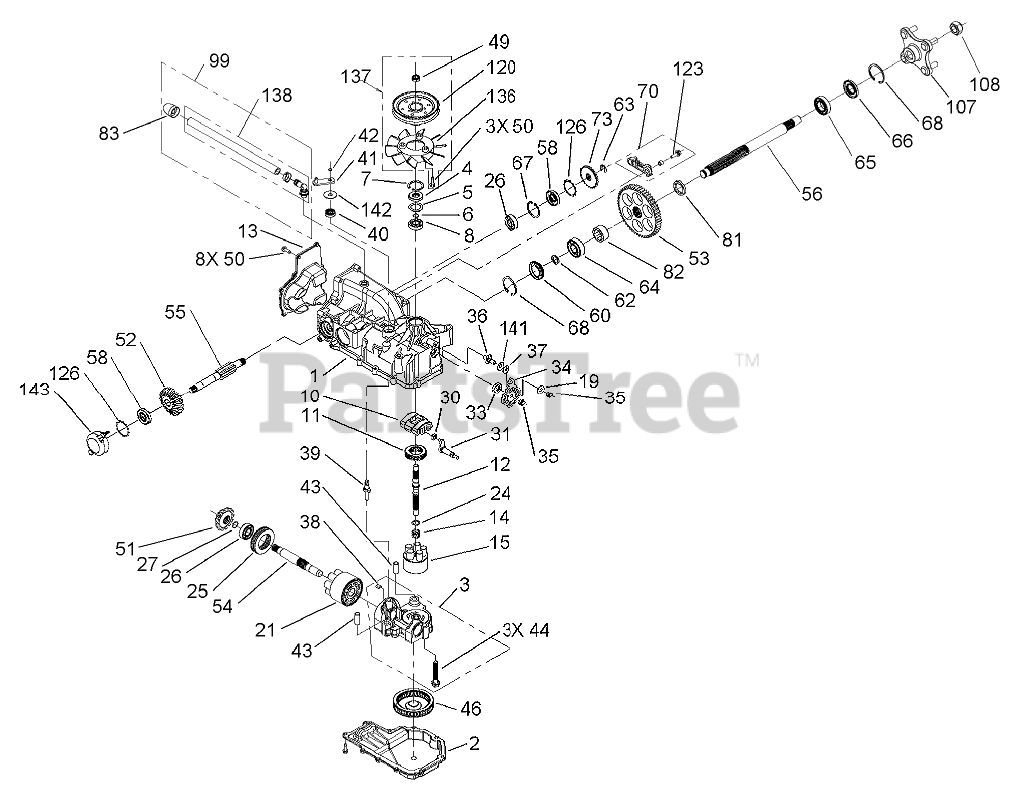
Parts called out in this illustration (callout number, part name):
1	Main Housing Kit
2	Housing-Lower
3	CENTER SECTION KIT ASM
4	SEAL-LIP
5	SPACER
6	RING-WIRE, RETAINING
7	RING-RETAINING
8	BEARING-SHAFT, BALL
10	SWASHPLATE-VARIABLE
11	BEARING-THRUST
12	Shaft-Input
13	COVER-BACK
14	SPRING-BLOCK
15	CYLINDER BLOCK ASM
19	WASHER-PIVOT
21	CYLINDER BLOCK ASM
24	WASHER-THRUST
25	BEARING-THRUST
26	BEARING-BALL
27	RING-RETAINING
30	GUIDE-SLOT
31	TRUNNION ASM
33	SEAL-LIP
34	ARM-CONTROL
37	PUCK-FRICTION
38	PLATE-BYPASS
39	ACTUATOR-BYPASS
40	SEAL-LIP
41	ARM-BYPASS
42	RING-RETAINING
46	FILTER
49	NUT-LOCK
51	GEAR-BEVEL, 14T
52	GEAR-BEVEL, 19T
53	GEAR-BEVEL, 53T
54	SHAFT-MOTOR
55	SHAFT-BRAKE
56	SHAFT-AXLE
58	SEAL-LIP
60	PLUG-SIDE SEAL
62	RING-AXLE, RETAINING
63	RING-RETAINING
64	Bearing-Ball
65	BEARING-BALL
67	RING-RETAINING
68	RING-RETAINING, AXLE
70	LH BRAKE ARM ASM
73	DISC-BRAKE
81	BUSHING-AXLE
82	BUSHING-AXLE
83	CAP VENT ASM
99	Breather Kit
107	HUB ASM
120	PULLEY
123	SCREW-HHF
126	RING-RETAINING
136	FAN
137	FAN PULLEY KIT
138	Hose/Fitting ASM
141	Washer
142	Washer
143	Cover-Brake, Plastic
